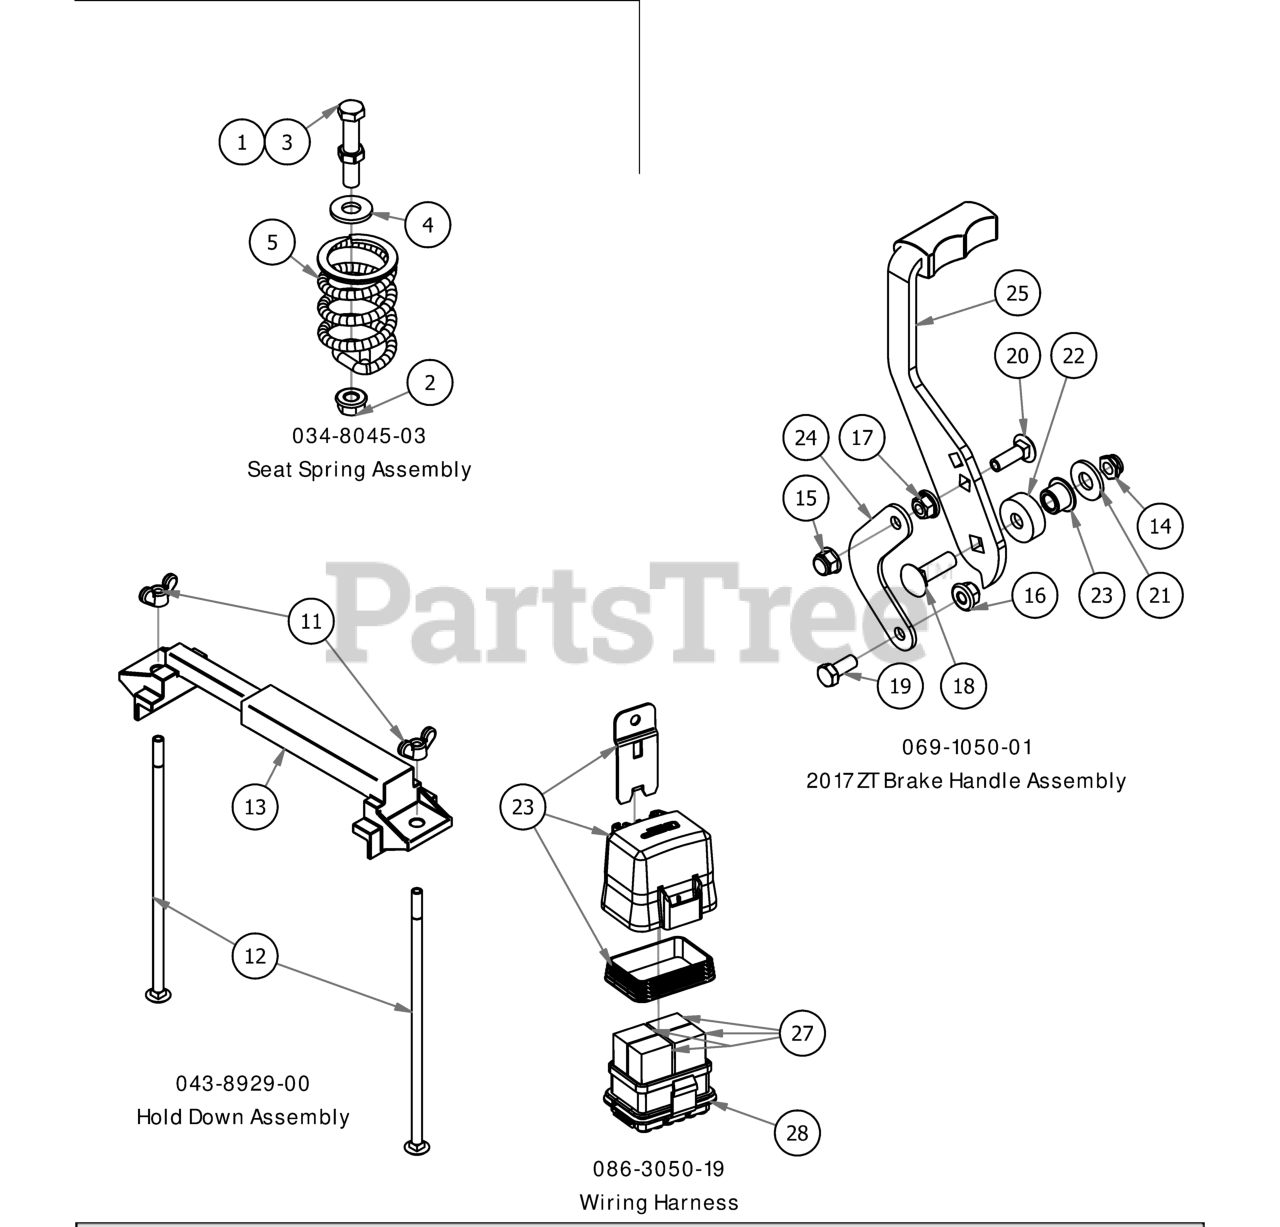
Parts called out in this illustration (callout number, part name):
1	3/8-16 Half Jam Nut
2	3/8" Flange Nut
3	3/8"-16 x 2" Gr 5 Hex Bolt
4	3/8" Flat Washer
5	Seat Spring
11	1/4" Wing Nut
12	1/4-20 X 8 Carriage Bolt
13	Battery Hold Down
14	3/8-16 Centerlock Half Nut
15	5/16-18 Nylon Insert Flange Nut (Black Cap)
16	5/16" Nylon Flange Nut
17	5/16" Flange Nut
18	3/8" x 1 1/4" Carriage Bolt
19	5/16" x 3/4" Hex Bolt
20	5/16" x 1" Carriage Bolt
21	3/8" Flat Washer
22	2015 Brake Lever Spacer
23	Bronze Bushing SF-1220-8
23	Relay Block Cover Replacement Kit
24	Brake Cable Adapter Bracket
25	Brake Handle
28	Wiring Harness (Includes Cover Replacement Kit and Relays)
